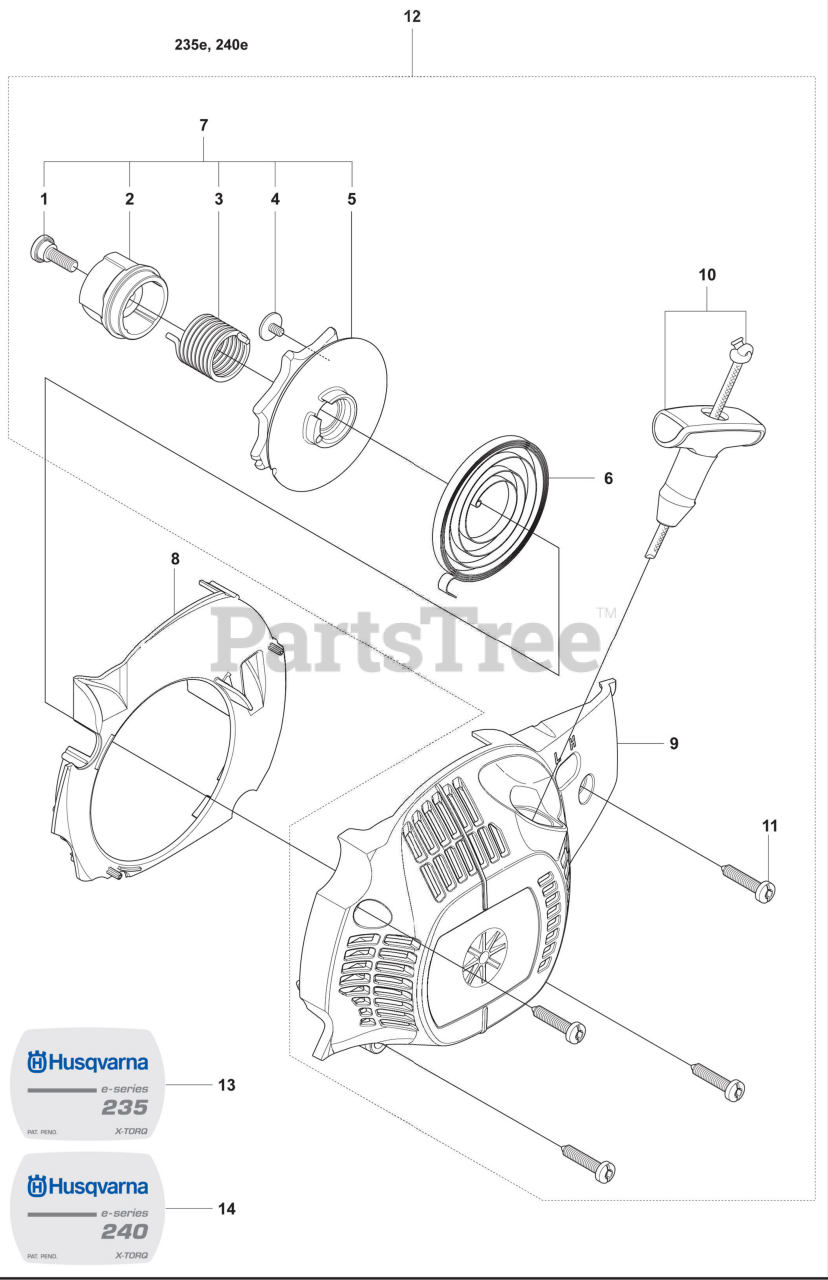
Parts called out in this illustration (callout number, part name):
1	SCREW SHOULDER
2	STARTER HUB EPS
3	SPRING EPS
4	SCREW, ROPE RETAINER
5	PULLEY-STARTER EPS
6	SPRING-RECOIL
7	KIT, EPS STARTER 235e/240e
9	FAN HOUSING
10	HANDLE & ROPE assy
11	SCREW, FAN HOUSING
12	KIT, complete EPS 235e/240e
13	DECAL 235e
14	DECAL 240e
